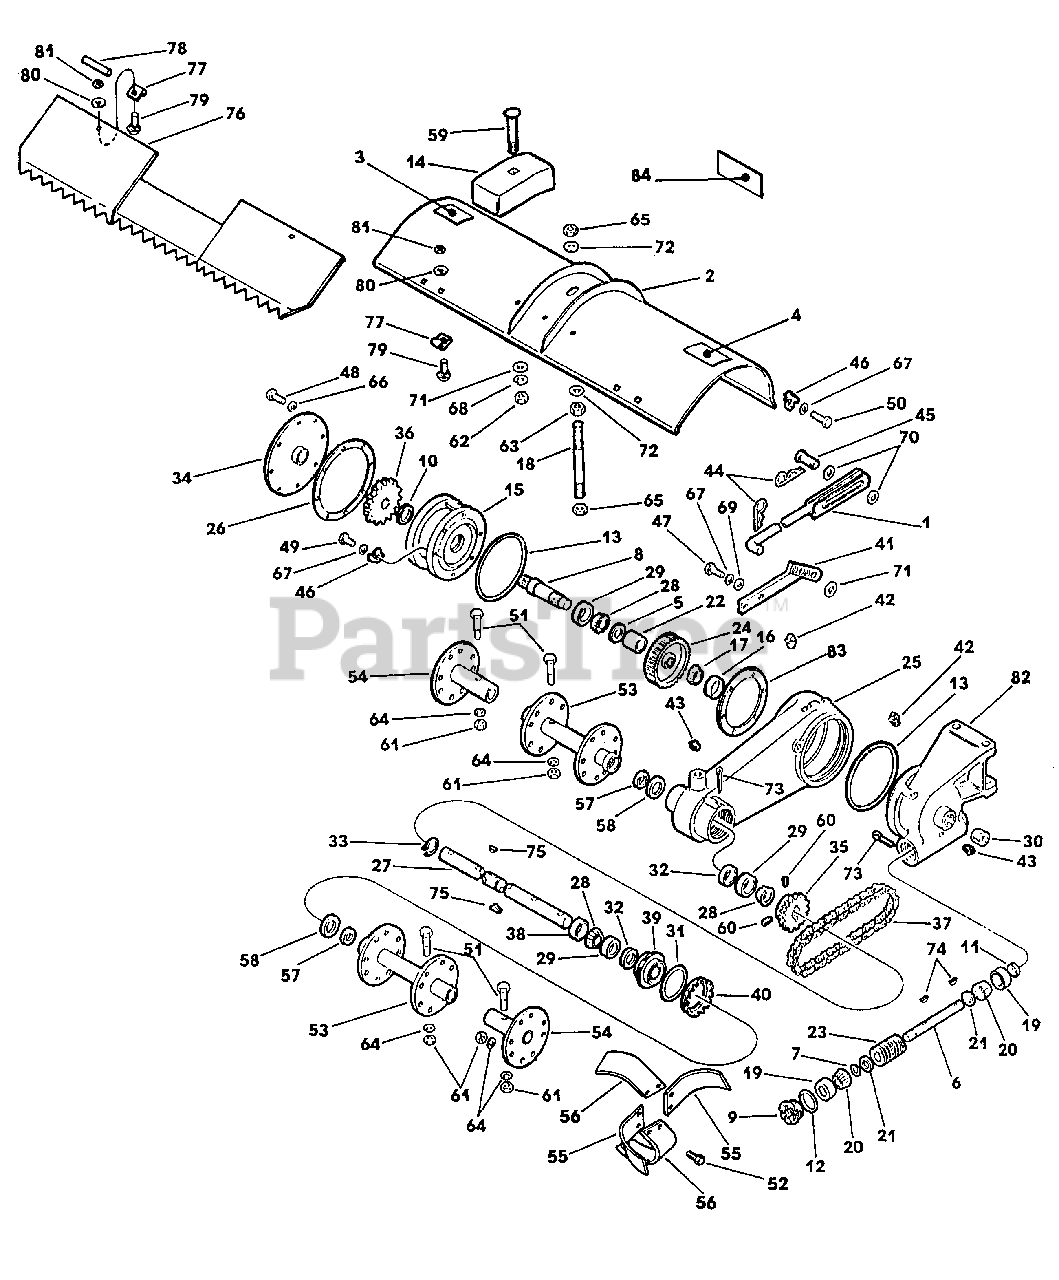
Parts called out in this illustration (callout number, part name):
1	Lift Rod Assembly
2	Tine Shield & Decal Assembly
3	Decal-Safety
4	Decal-Danger
5	Shim-Bearing Adjustment
6	Worm Shaft
7	Snap Ring
8	Shaft & Sleeve Assembly
9	Plug-Bearing Adjustment
10	Seal
11	Seal
12	O-Ring
13	O-Ring
14	Tiller Weight
15	Bearing Plate
16	Bearing Cup
17	Bearing Cone
18	Tine Shield Stud
19	Bearing Cup
20	Bearing Cone
21	Worm Spacer
22	Worm Wheel Spacer
23	Worm
24	Worm Wheel
25	Chain Case
26	Gasket-Cover
27	Tine Shaft
28	Bearing Cone
29	Bearing Cup
30	Pipe Plug-Socket
31	O-Ring
32	Oil Seal
33	Snap Ring
34	Chain Case Cover Assembly
35	Sprocket-15T
36	Sprocket-19T
37	Chain, #60 includes #7042149 Connector Link
38	Spacer
39	Plug-Bearing Adjustment
40	Lock Ring
41	Lift Arm Assembly
42	Vent Plug Assembly
43	Pipe Plug
44	Spring Clip
45	Clevis Pin
46	Lug Washer
47	Cap Screw, Hex Hd
48	Cap Screw, Hex Hd
49	Cap Screw, Hex Hd
50	Cap Screw, Hex Hd
51	Cap Screw, Hex Hd
52	Tine Bolt
53	Inner Tine Hub Assembly
54	Outer Tine Hub Assembly
55	Tine-R.H
56	Tine-L.H
57	Inner Felt Seal
58	Intermediate Felt Seal
59	Bolt, Carriage
60	Setscrew, Hex Socket Hd. Cup Pt
61	Nut, Hex
62	Nut, Hex
63	Nut, Hex Jam
64	Washer, Spring Lock
65	Nut, Hex Self Locking
66	Washer, Spring Lock
67	Washer, Spring Lock
68	Washer, Spring Lock
69	Washer, Flat SAE
70	Washer, Flat
71	Washer, Flat
72	Washer, Flat
73	Pin, Cotter
74	Key, Woodruff
75	Key, Hypro
76	Guard Assembly
77	Hinge
78	Hinge Pin
79	Bolt, Carriage
80	Washer, Spring Lock
81	Nut, Hex
82	Gear Case
83	Gasket-Gear Case
84	Decal-Danger (Mount On Tractor Dash)
